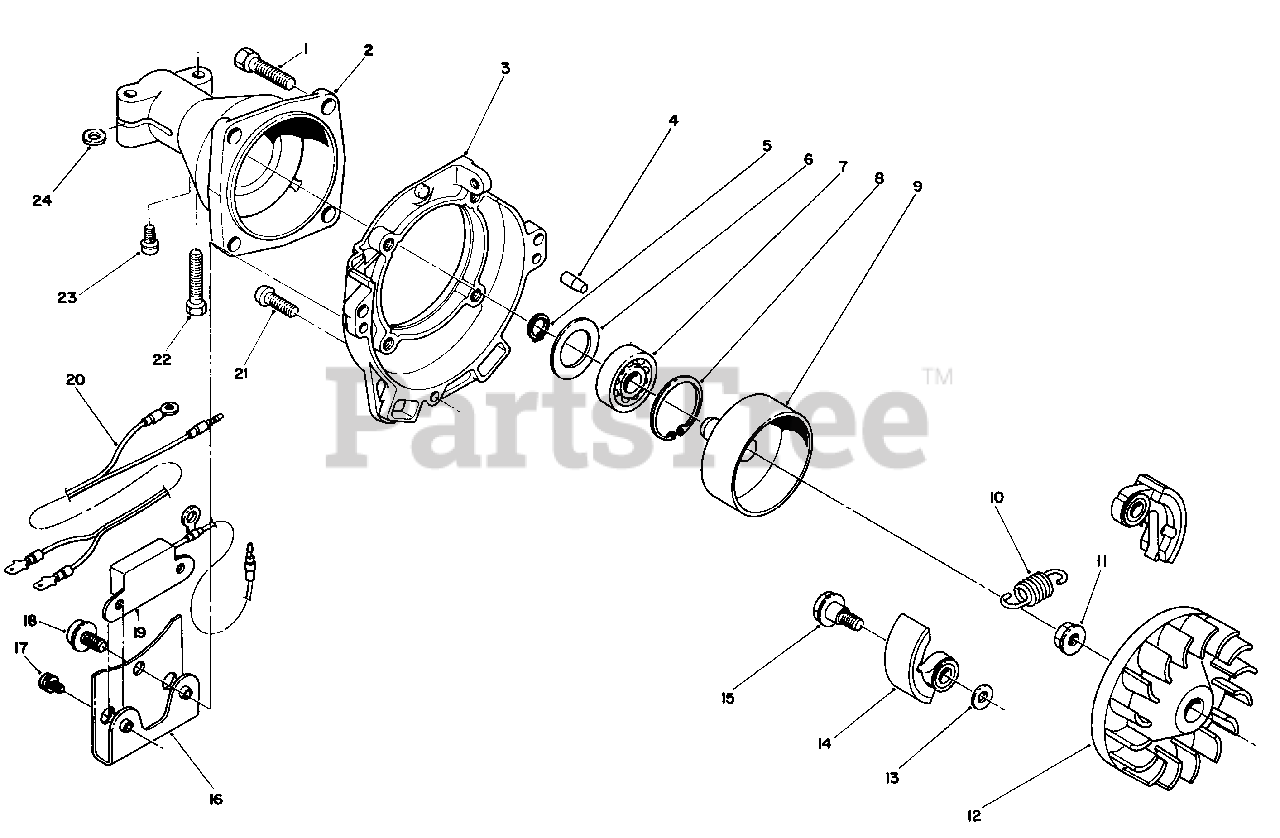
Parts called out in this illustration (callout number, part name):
1	Screw & Washer
2	Case, Clutch
3	Case, Fan
4	Pin, Dowel
5	Snap Ring
7	Bearing, Ball
8	Snap Ring
9	Drum, Clutch
10	Spring
11	Nut, Conical Spring
14	Shoe, Clutch
15	Bolt, Clutch
16	Bracket, Unit
17	Screw & Washer
18	Screw & Washer
19	Unit, Transistor
20	Wire, Lead
21	Bolt & Washer
22	Bolt & Washer
23	Screw & Washer
24	Washer, Spacer
